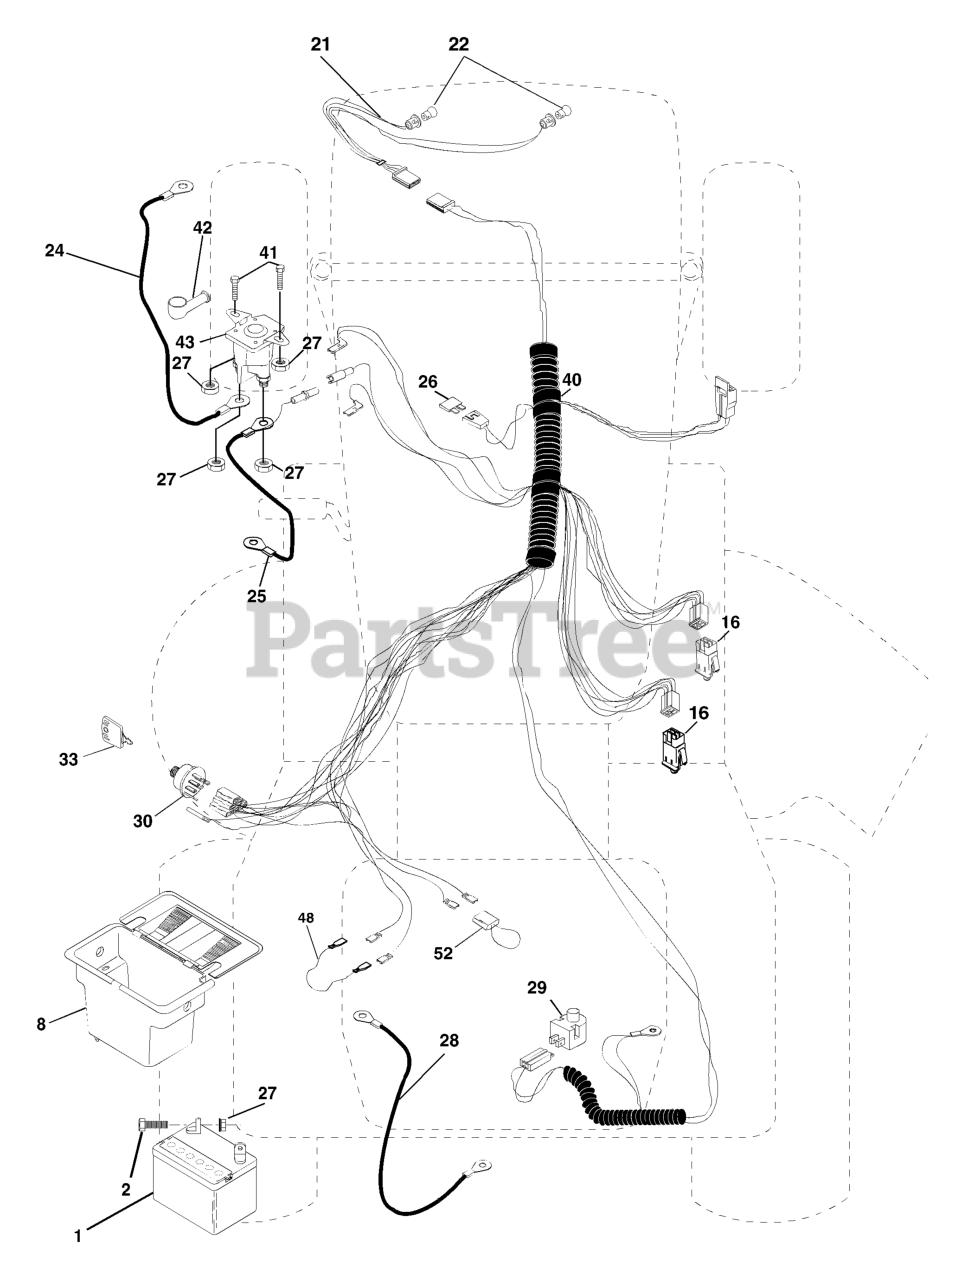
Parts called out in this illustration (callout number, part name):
1	BATTERY 12 VOLT 25 AMP
2	BOLT.HEX.1/4.X.3/4.DICHROMATE
8	CASE BATTERY MECH HINGE
16	SWITCH INTERLOCK
24	BATTERY CABLE GT
25	CABLE BATTERY
26	FUSE 20AMP
27	NUT
28	CABLE T
29	RP.SWITCH.PLUNGER.NC.GRAY
30	IGNITION SWITCH
33	KEY MLD GEN DELTA
40	HARNESS, IGN. LTH120
41	BOLT
42	TERMINAL COVER
43	REPL BY 532 1461-54
48	ADAPTER.AMMETER
52	WIRE PROTECTION LOOP
